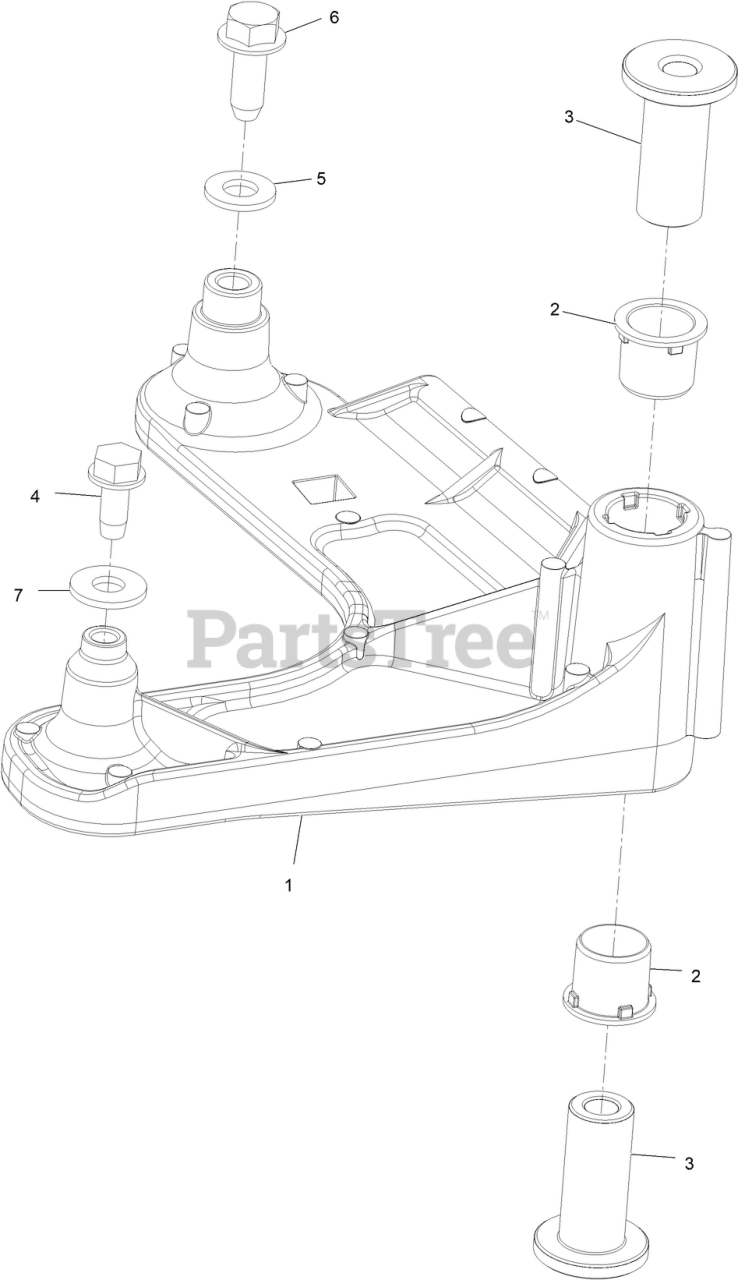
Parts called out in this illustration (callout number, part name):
1	Arm-Idler, Deck
2	BUSHING, IGUS
3	Spacer, Idler Pivot
4	SCREW-THD ROLL, HWH
5	WASHER-FLAT
6	SCREW-FORMING, THREAD
7	WASHER-FLAT
